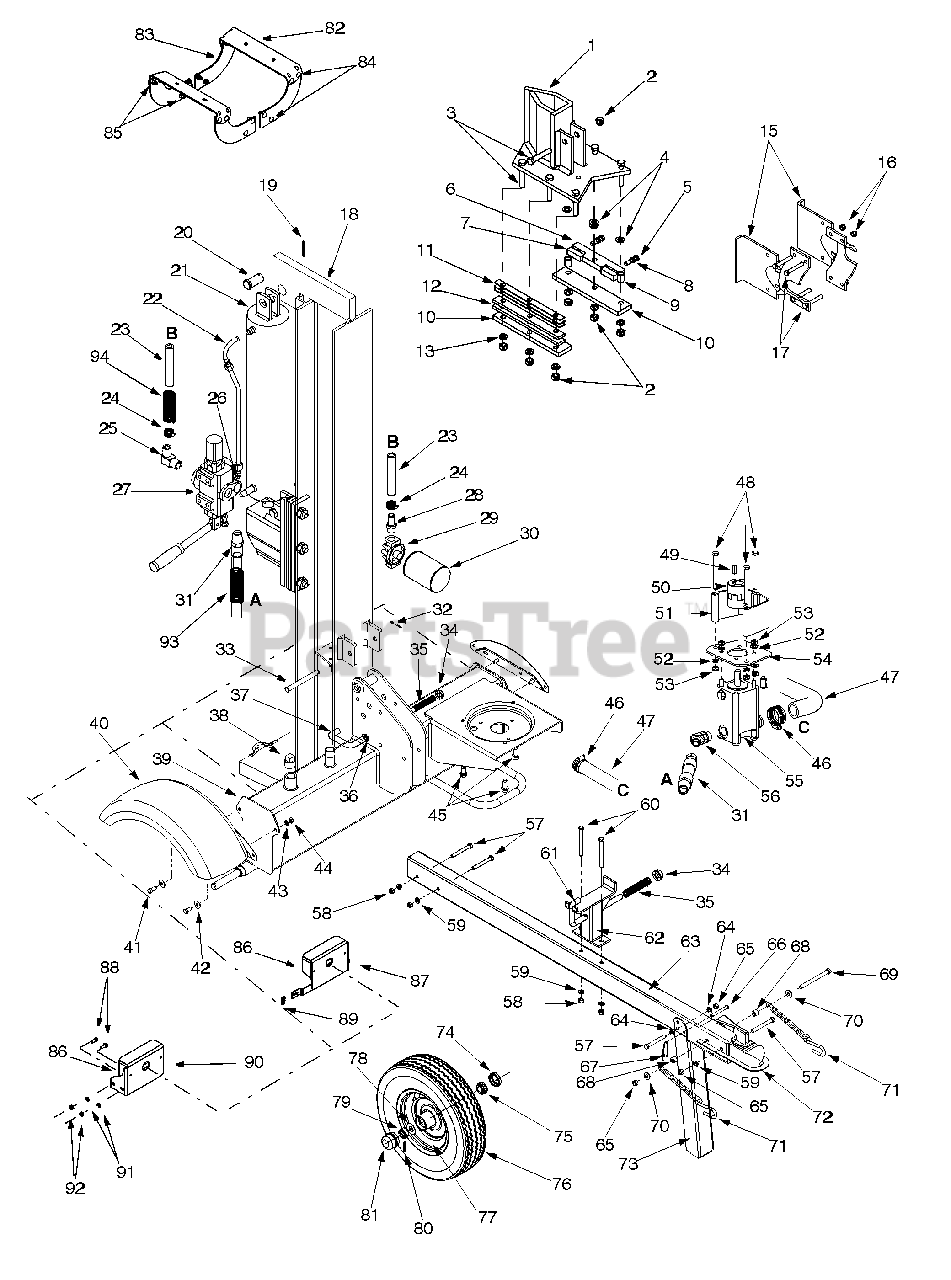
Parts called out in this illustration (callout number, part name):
2	Lock Nut 1/2-20
3	Hex Cap Screw 1/2-20 x 2.75
4	Flat Washer .531 x .93 x .090
5	Hex Cap Screw 3/8-24 x 1.5
7	Adjustable Gib
8	Hex Jam Nut 3/8-24
9	Spacer
13	Lock Washer 1/2
13	Lock Nut 1/2-20
17	Hex Cap Screw 3/8-16 x 2.5
20	Clevis Pin
22	Hydraulic Tube
23	Return Hose 3/4" ID x 44" Lg
24	Hose Clamp 5/8"
25	Return Elbow
26	90 Degree Solid Male Adapter
28	3/4" Hose Adapter
29	Filter Housing
30	Oil Filter
31	High Pressure Hydraulic Hose
32	Cotter Pin 1/8" Dia
33	Hinge Pin 1/2 x 4.8" Lg.
35	Comp. Spring 4" Lg.
36	Flat Washer .635 ID x .93 OD
37	Locking Rod
38	Pipe Plug
42	5/16 Washer
43	Lock Washer 5/16
44	Hex Nut 5/16-24
45	Hex Washer Screw 3/8-16 x 1.
46	Hose Clamp
47	Suction Hose
48	Hex Screw 5/16-24 x 3.25
49	Sq. Key 3/16" x .75
50	Flexible Coupling (Stamped L075) .750 x .500 ID
50	Flexible Coupling (Stamped L075) .875 x .500 ID
50	Flexible Coupling (Stamped L075) .875 x .437 ID
51	Coupling Shield
52	L-Washer 5/16" ID
53	Hex Nut 5/16-24
55	Gear Pump (11 gpm)
55	Gear Pump (9.5 gpm)
56	45 Degree Elbow
57	Hex Bolt 3/8-16 x 3" Lg.
58	Hex Nut 3/8-16
59	L-Washer 3/8" ID
60	Hex Bolt 3/8-16 x 4" Lg.
61	Locking Rod
64	Flat Washer 3/8
65	Hex Lock Nut 3/8-16
66	Clevis Pin 5/16 x 2.5"
67	Spring Pin
68	Spacer 3/8" ID x .625' OD
69	Hex Bolt 3/8-16 x 4" Lg.
70	Flat Washer 3/8" ID x .87" OD
71	Chain - Tow Hitch
72	Hitch Coupler
75	Bearing Cone
76	Wheel Assembly
77	Rim Assembly
78	Flat Washer .76" ID x 1.5" OD
79	Slotted Nut 3/4-16
80	Cotter Pin 5/32" x 1-1/4" Lg.
85	Flanged Lock Nut, 3/8-16
86	Taillight Assembly
89	Speed Clip
92	Hex Nut, 5/16-24
93	Hose Guard
94	Hose Guard
